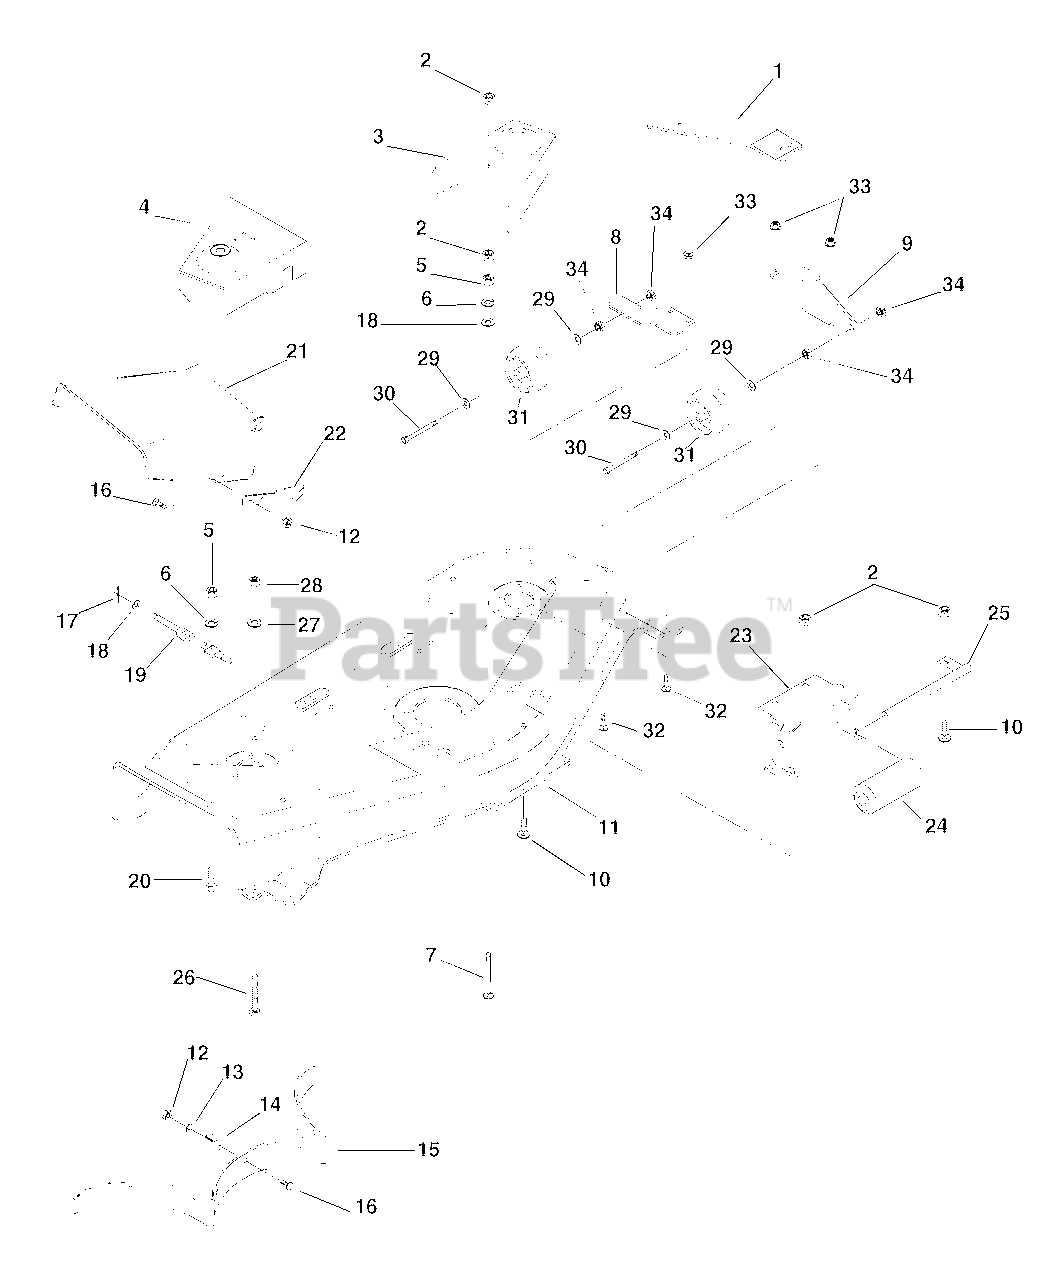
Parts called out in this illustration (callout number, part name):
2	@NUT-LK-CTR .31-18 YWZC
3	COVER, RIGHT HAND
4	COVER, LEFT HAND
5	@NUT-HEX .31-18 YWZC
6	WSHR-LK .312X.097 HVY YWZC
7	BLT-RDHDSQNK .31-18X3.25 SHTPL
8	BRACKET, LEFT REAR
9	BRACKET, LEFT FRONT
10	@BLT-RDHDSQNK .31-18X.75 G5YZ
11	MOWER PAN W/DECALS 48"- ORANGE
12	@NUT-LK-CTR .25-20 YWZC
13	@WSHR-FL-STL.281X.62X.065 YWZC
14	BAFFLE TAB
15	BAFFLE
16	BLT-RDHDSQSHNK.25-20X.50 YWZC
17	@PIN-CTR .09X.75 EXTPRSQCT YWZ
18	@WSHR-FL-STL.406X.812X.065 YWZ
19	HINGE PIN
20	@BLT-HEX .31-18X.75 GR5 YWZC
21	CHUTE EXTENSION
22	FLAT SPRING - ORANGE
23	BRACKET, ROLLER
25	ROLLER SHAFT
26	@BLT-HEX .38-16X2.50 GR5 YWZC
27	WSHR-LK .375X.130 YWZC
28	@NUT-HEX .38-16 YWZC
29	WSHR-FL-NYL .518X1.000X.080
30	@BLT-HEX .50-13X4.50 GR5 YWZC
31	WHEEL 5 X 3
32	@BLT-RDHDSQNK .31-18X.75 G5YZ
33	@NUT-SPNLK-FLG .312-18 YWZC
34	@NUT-LK-CTR .50-13 YWZC
